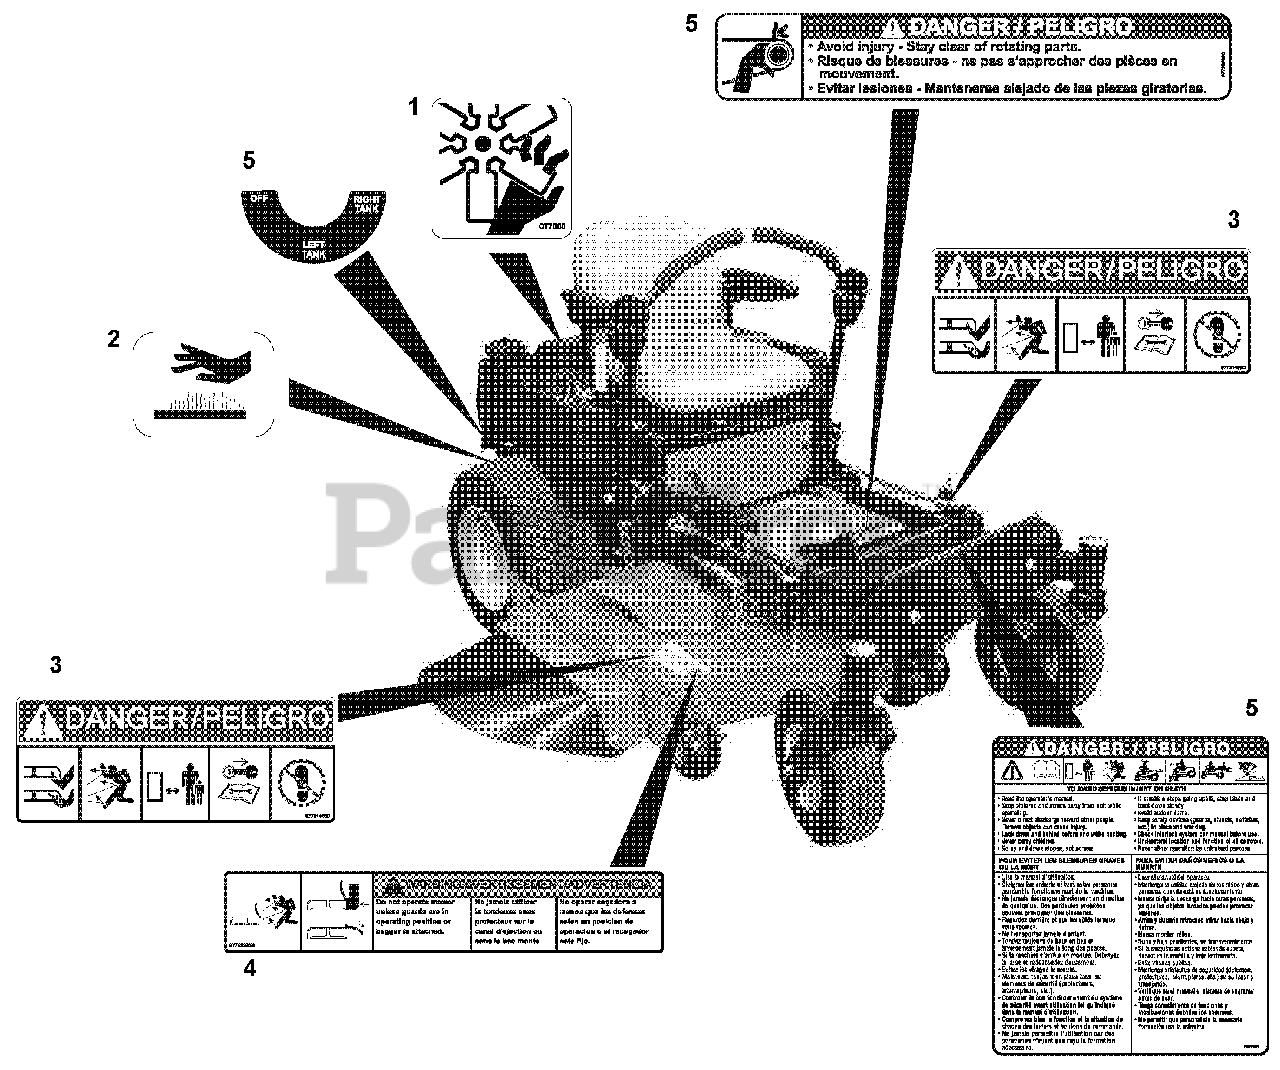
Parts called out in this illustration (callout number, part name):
1	Decal, Danger Fan
2	Decal, Hot Surface
3	Decal, Mower Pan Head Danger
4	Decal, Warning
5	Set, Decal Common Danger/Fuel
